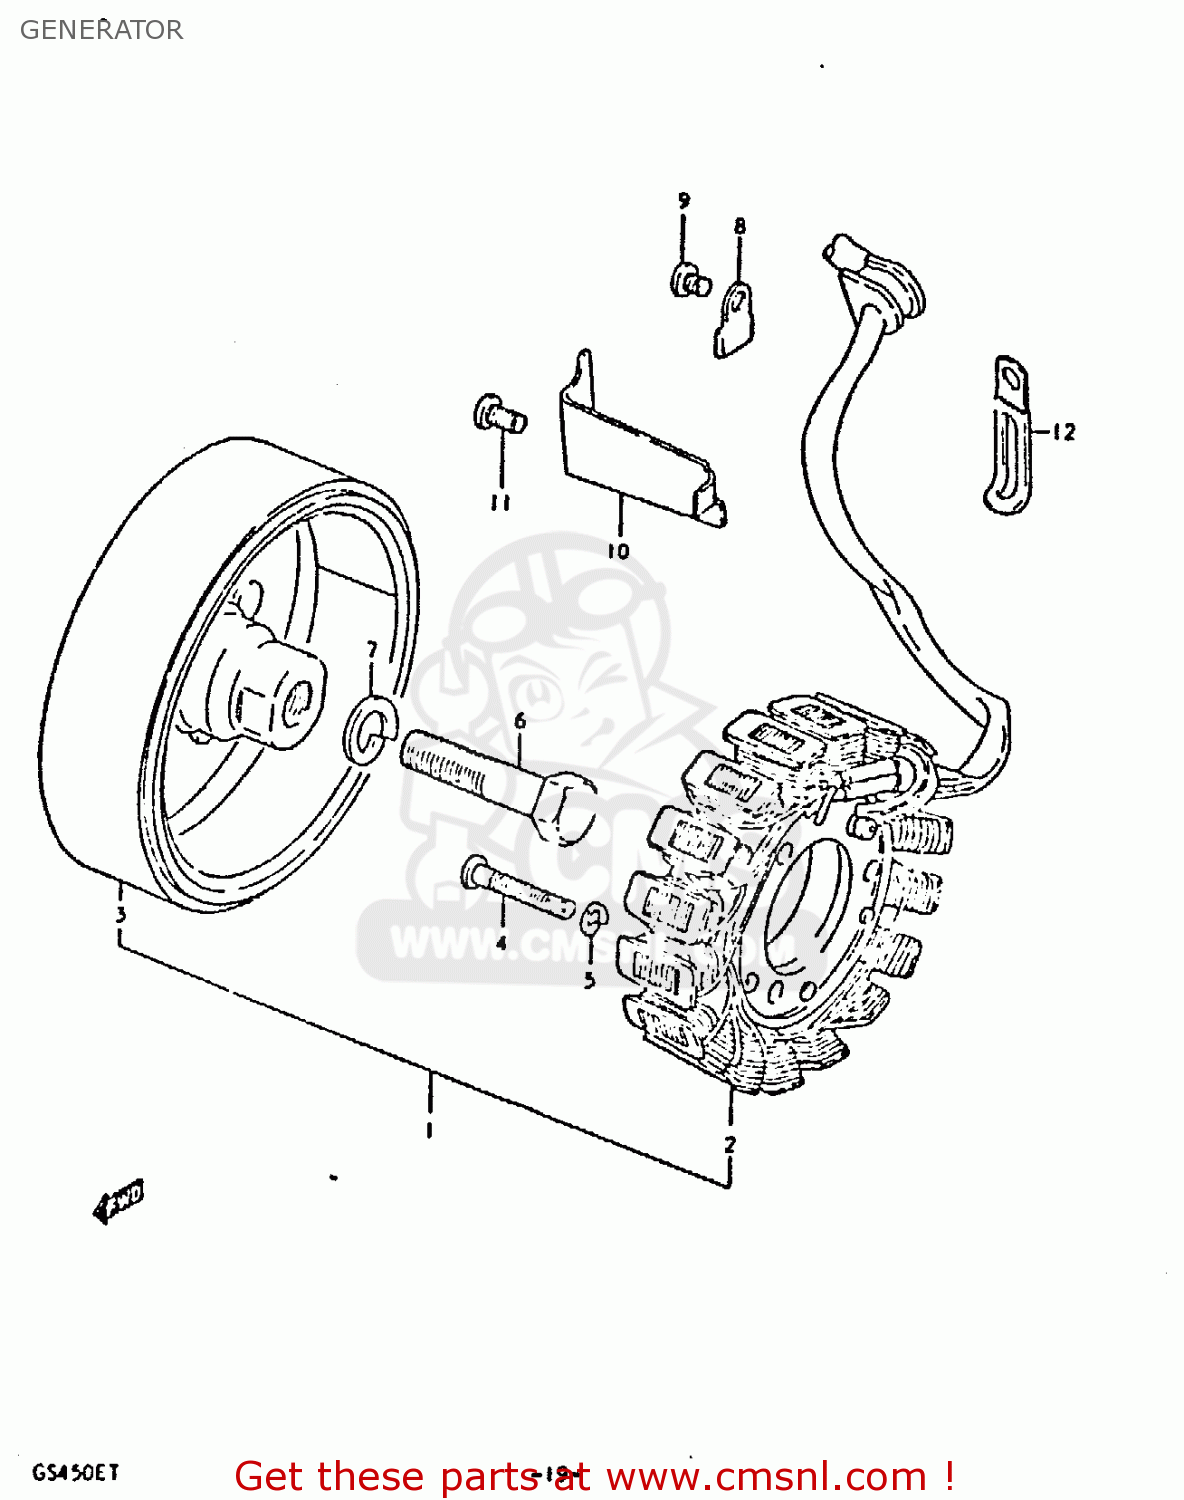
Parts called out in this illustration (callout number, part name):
1	GENERATOR ASSEMBLY
2	STATOR ASSEMBLY
3	ROTOR ASSEMBLY
4	SCREW
5	LOCK WASHER
6	BOLT 12X45
7	WASHER,LOCK 12
8	CLAMP,GENERATOR LEAD WIRE
9	SCREW
10	CLAMP,GENERATOR LEAD WIRE
11	SCREW
12	CLAMP L:35
